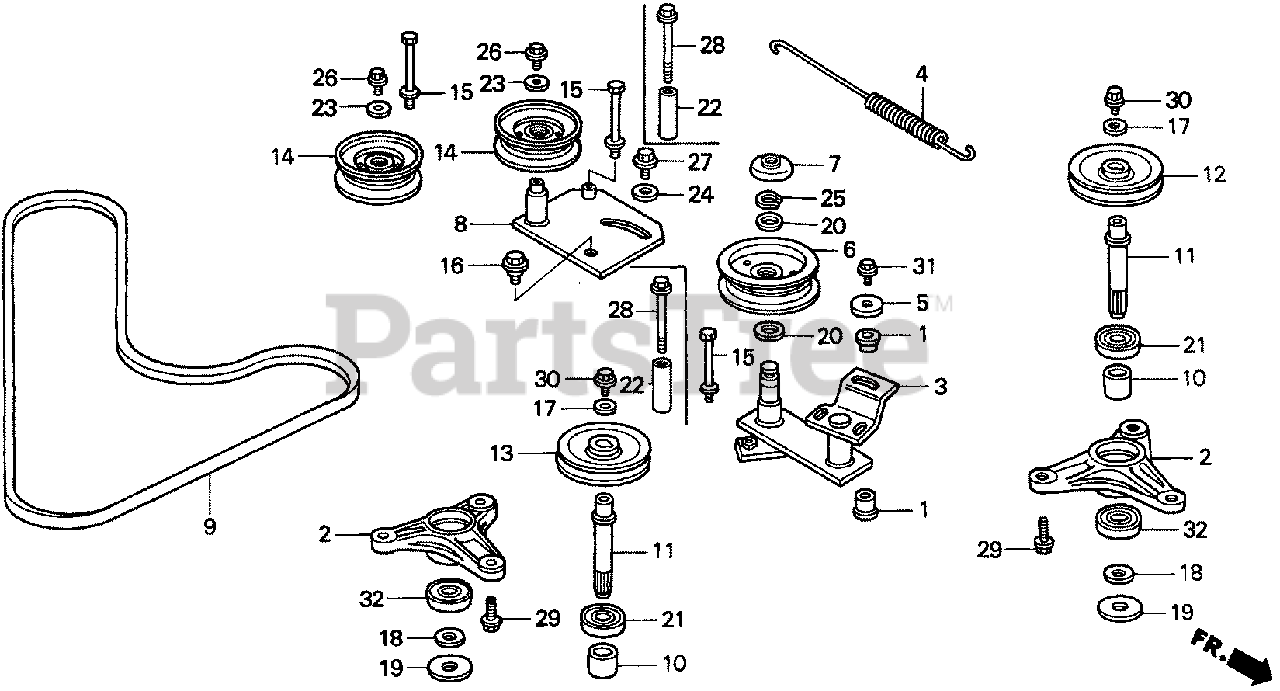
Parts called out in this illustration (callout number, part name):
1	BUSH (15X19X22)
2	HOUSING, BEARING
3	ARM, TENSIONER (DECK)
4	SPRING, TENSIONER ARM
5	CAP, TENSION ARM
6	ROLLER, TENSIONER (DECK)
7	DUST COVER, TENSION PULLEY (NOT AVAILABLE)
8	ARM, BELT ADJUSTING
9	V-BELT, BLADE (SB-98)
10	COLLAR, BLADE SHAFT
11	SHAFT, BLADE (112.5MM)
12	PULLEY, BLADE (115)
13	PULLEY, BLADE (120)
14	PULLEY, IDLER
15	BOLT, BELT STOPPER
16	BOLT, ADJUSTING ARM
17	WASHER (10.5X27X4)
18	WASHER, THRUST (20MM)
19	WASHER, BLADE HOLDER
20	WASHER (17.3X25)
21	BEARING, RADIAL BALL
22	COLLAR, BELT STOPPER (8.6X15X45)
23	WASHER, PLAIN (6MM)
24	WASHER, PLAIN (8MM)
25	CIRCLIP (OUTER) (17MM)
26	BOLT, FLANGE (6X12)
27	BOLT, FLANGE (8X16)
28	BOLT, FLANGE (8X55)
29	BOLT, FLANGE (10X28)
30	BOLT, FLANGE (10X16) (NA USE ALT:95700-10016-08)
31	BOLT, FLANGE (6X12)
32	BEARING, RADIAL BALL (6204UU)
